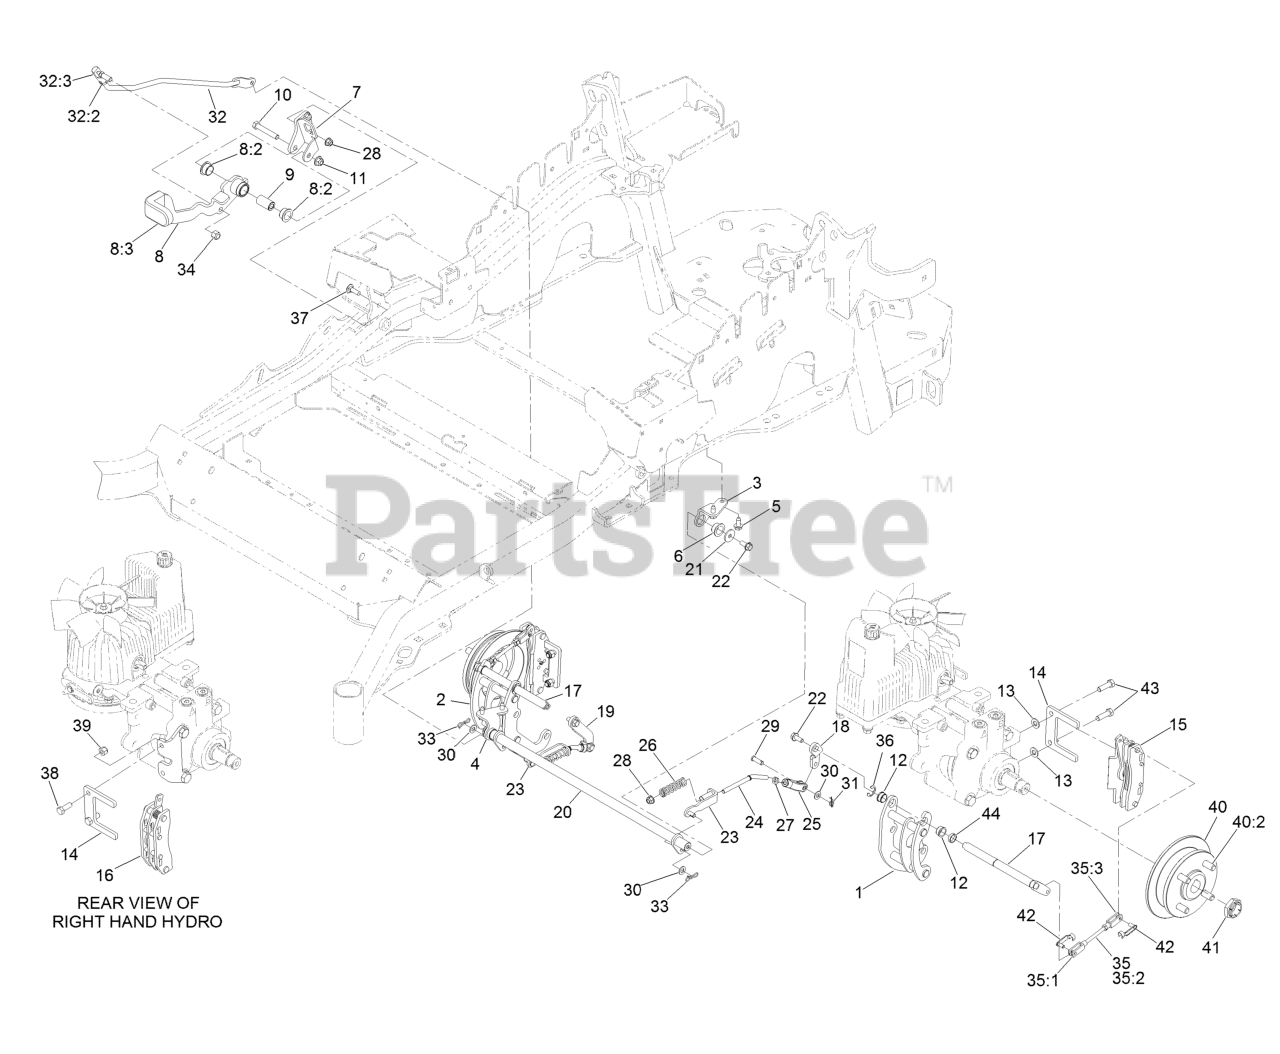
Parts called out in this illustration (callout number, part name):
1	Mount-Bellcrank, LH
2	Mount-Bellcrank, RH
3	Mount-Pivot, LH
4	Mount-Pivot, RH
5	Screw-HWHTF
6	Bushing-Flange
7	Bracket-Mount
8	Brake Lever ASM W/ Grip
8:2	Bushing-Flange
8:3	Grip-Lever
9	Handle-Pivot, Brake
10	Screw-HH
11	Nut-HF, NI
12	Bushing
13	Washer-Flat
14	Plate-Mount, Brake
15	Caliper-Brake
16	Caliper-Brake, RH
17	Bellcrank
18	Arm-Inner, LH
19	Arm-Inner, RH
20	Shaft-Cross
21	Washer-Flat
23	Bracket-L
24	Linkage-Mid
25	Yoke-Offset
26	Spring-Compression
27	Nut-Jam
28	Nut-HF, NI
29	Pin-Clevis
30	Washer-Plain
31	Pin-Cotter, Locking
32	Front Linkage ASM
32:2	End-Tie Rod, RH
32:3	Nut-HJ
33	Pin-Cotter, Locking
34	Nut-Lock
35	Rear Linkage ASM
35:1	Yoke
35:2	Linkage, Rear
35:3	Nut-Jam
37	Bolt-CARR
38	Screw-HH
39	Nut-Lock, NI
40	Wheel Hub ASM
40:2	Stud-Wheel
41	Locknut
42	Pin-Clevis, Spring
43	Screw-Lock, Patch
